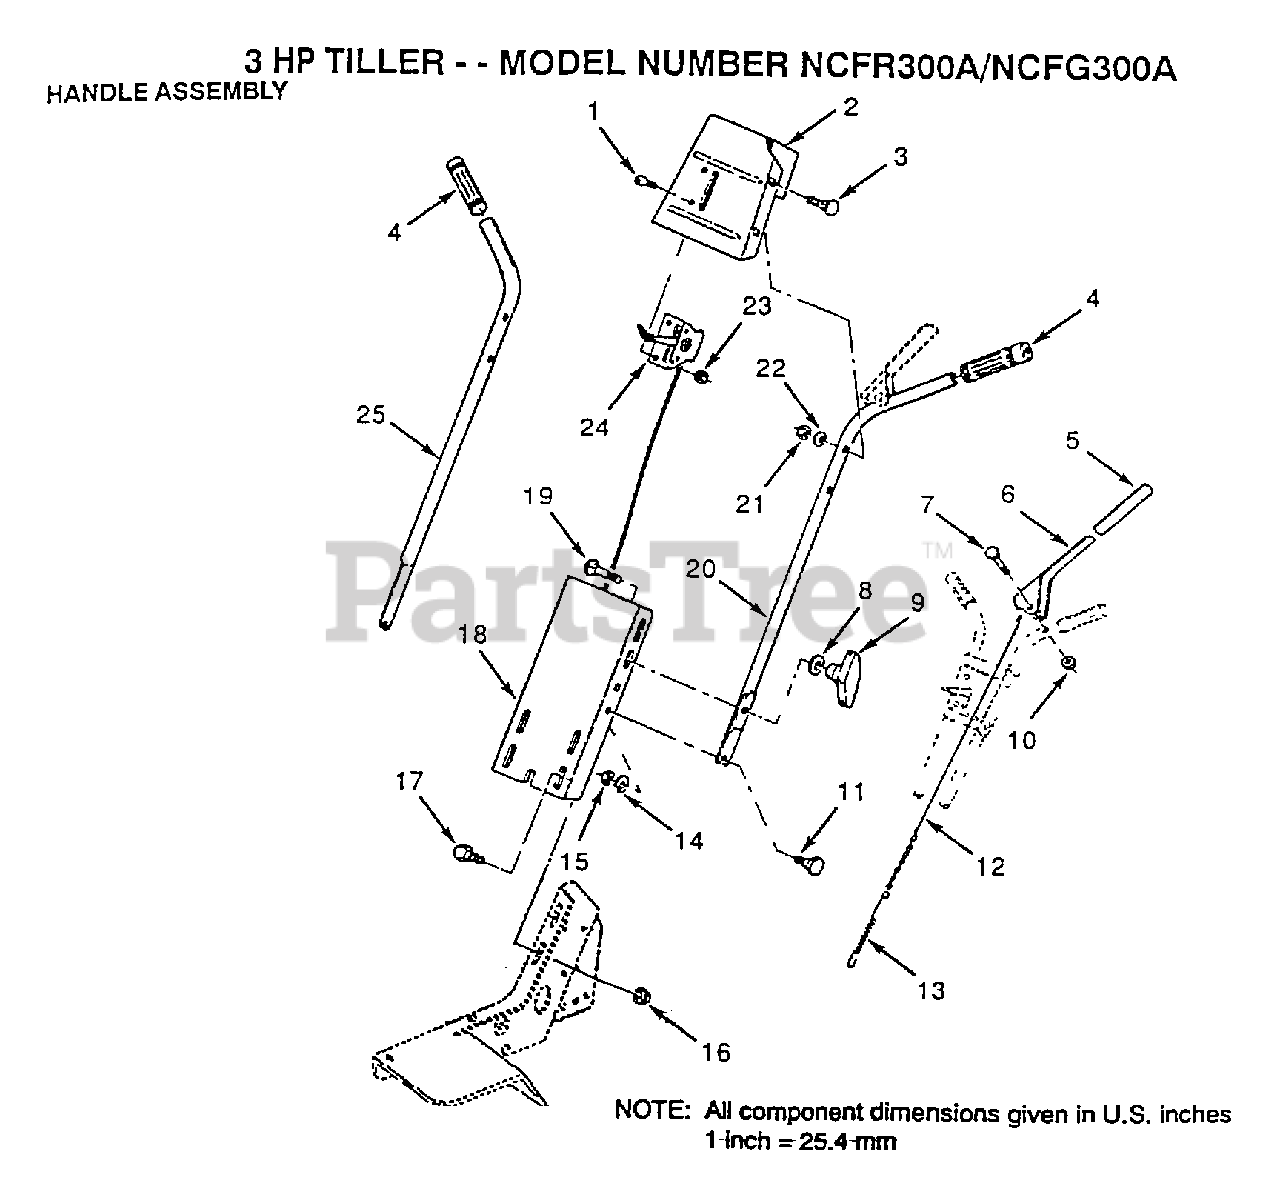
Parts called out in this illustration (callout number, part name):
1	SCREW
2	BRKT HDLE TI
3	BOLT
5	GRIP T
7	BOLT.HEX.5/16-1.5
8	WASHER
13	SPRING EXT TI
14	LOCKWASHER
15	NUT.HEX.5/16-18
16	NUT
17	BOLT
18	"PANEL,HANDLE"
19	BOLT
22	WASHER
